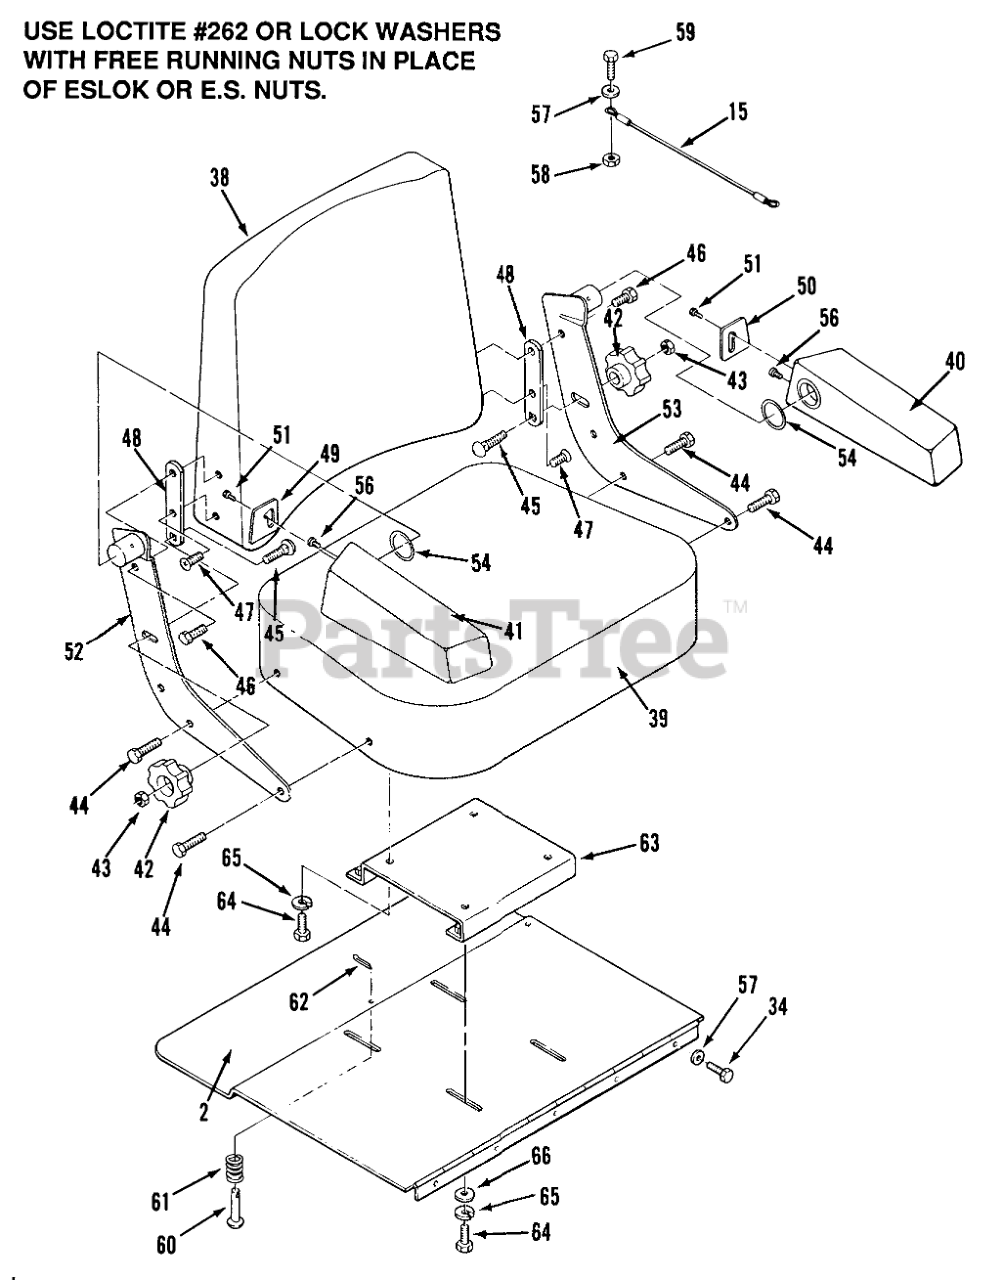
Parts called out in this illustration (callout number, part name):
2	Seat Mounting Bracket
15	Cable
34	Bolt
38	Seat Back
39	Seat Bottom
40	ARM REST LH
41	ARM REST RH
42	Knob-Lumbar Control
43	LOCK NUT
44	Bolt
45	Bolt
47	Screw-Phillips Hd
48	Lumbar Friction Plate
49	ARM REST PLATE RH
50	ARM REST PLATE LH
51	SCREW PAN HD 10-16X5
52	Back Support LH
53	BACK SUPT LH
54	WASHER
56	SHCS 1/4-20 X 1/2
57	WASHER
58	Nut
59	Bolt
61	SPRING-SEAT SWITCH
62	Cotter Pin
63	ASS'Y-SUPPORT SEA B
64	Bolt
65	LOCKWASHER
66	Washer
